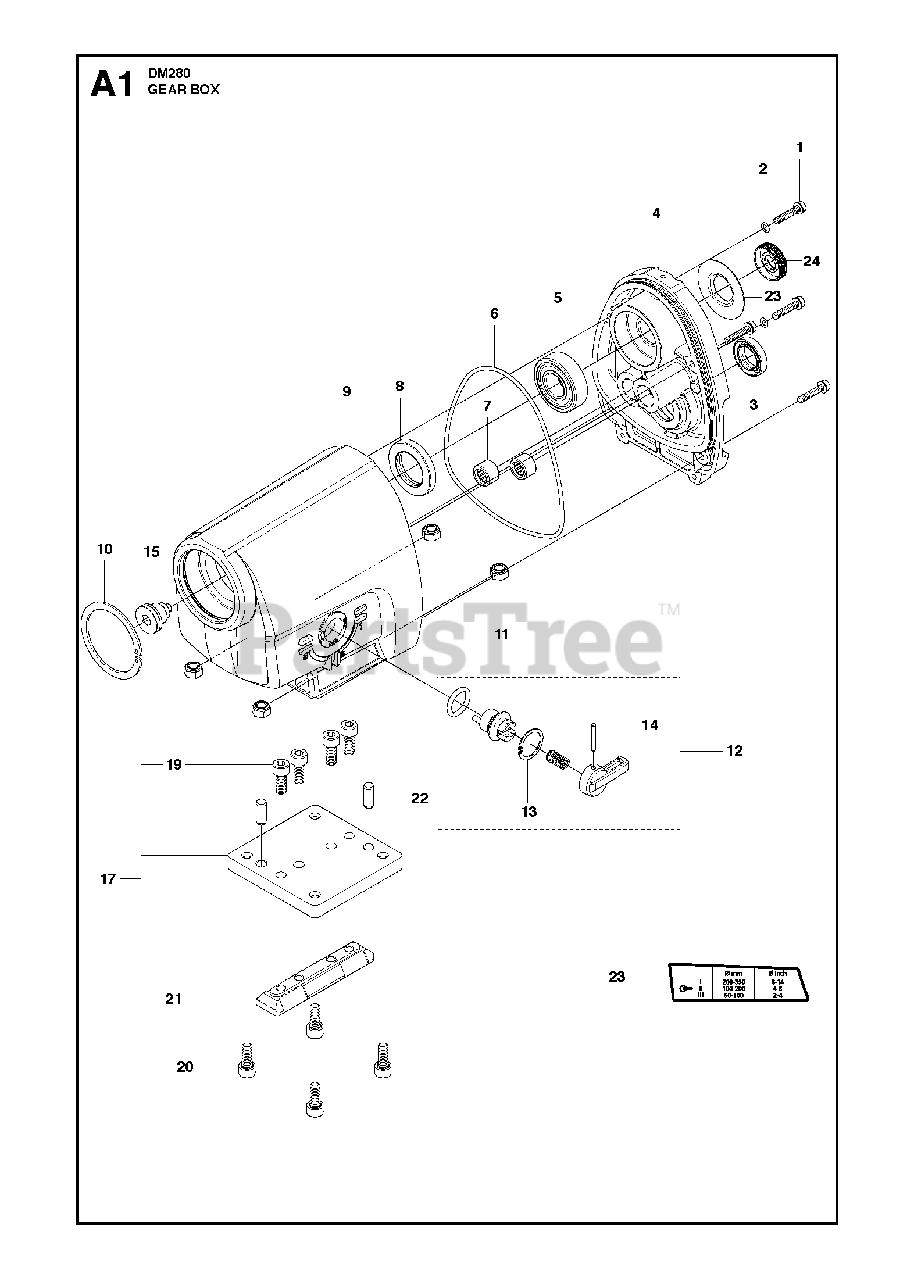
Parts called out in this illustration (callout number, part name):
1	SCREW IHSCFM
5	BALL BEARING
7	NEEDLE BEARING
11	HEXAGON LOCKING NUT
14	PARALLEL PIN
22	PARALLEL PIN
23	LABELLow speed version
23	LABELHigh speed version
